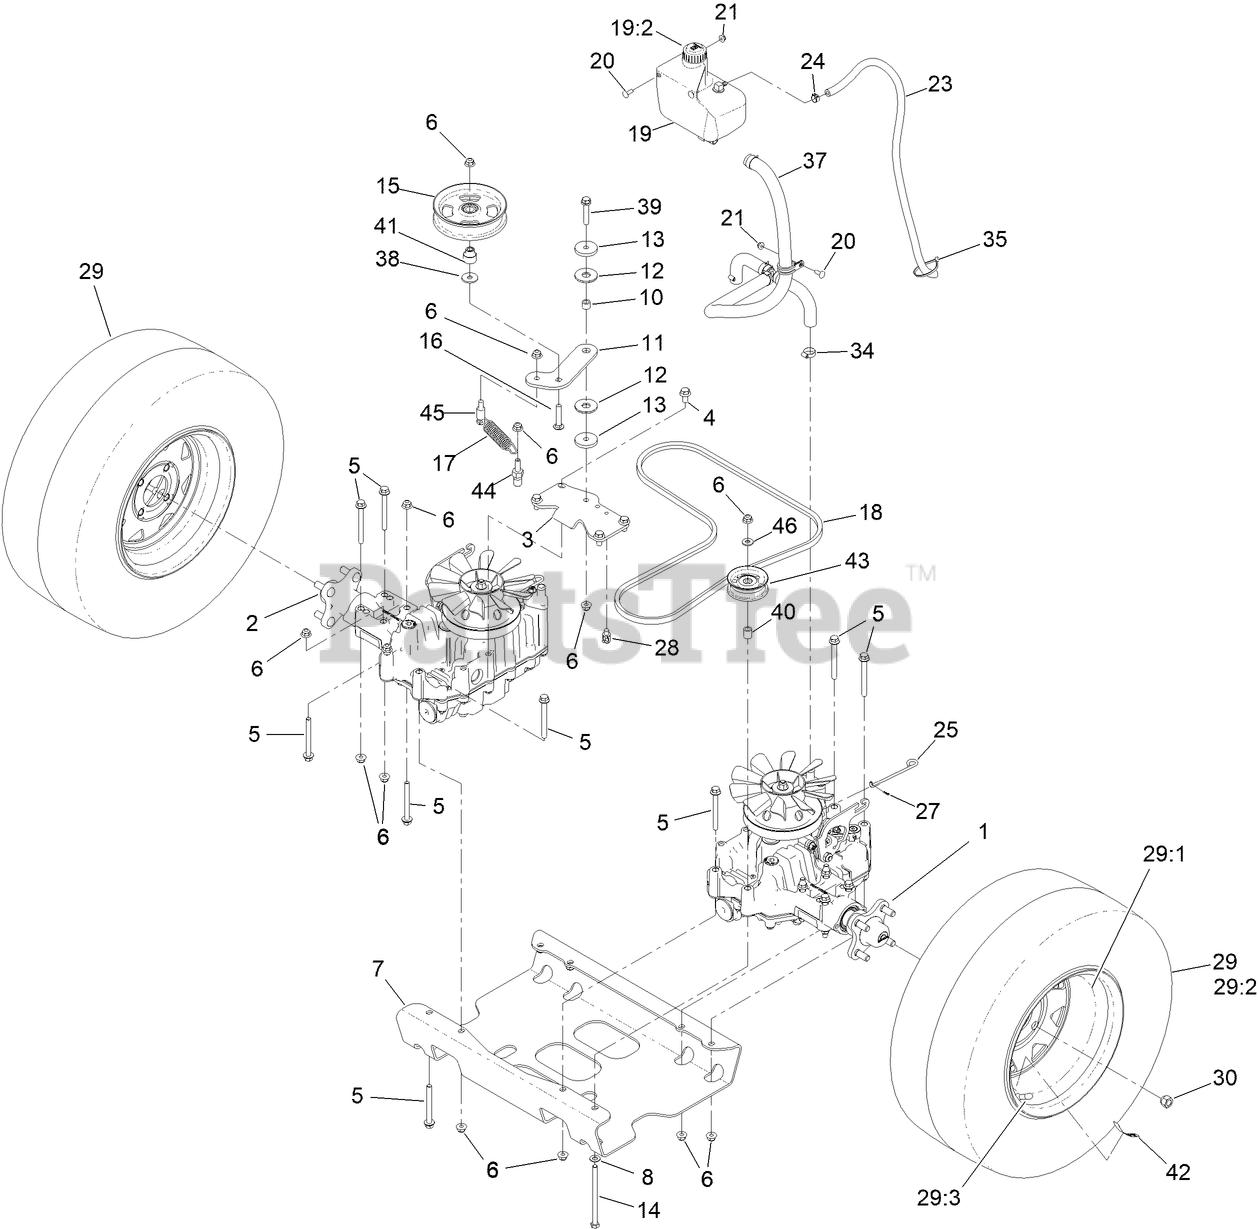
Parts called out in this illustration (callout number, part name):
1	LH TRANSMISSON (TZT13SY)
2	RH TRANSMISSON (TZT13SX)
3	PLATE, SUPPORT, TRANSAXLE
4	SCREW-BSHS
5	SCREW-HHF
6	NUT-HF, NI
7	PLATE-HYDRO
8	WASHER-FLAT
10	BUSHING-LEVER, LIFT
11	PLATE-ARM, IDLER
12	WASHER-FRICTION, COMPOSITE
13	WASHER-PLAIN
14	SCREW-HH
15	PULLEY-IDLER,FLAT
16	SCREW-CARR
17	SPRING-EXTENSION
18	BELT-V
19	TANK-HYD
19:2	CAP-VENTED
21	NUT-HF
23	HOSE-FUEL
24	CLAMP-HOSE
25	ROD-BYPASS
27	PIN-HAIR
28	CLIP-TIE
29	WHEEL AND TIRE ASM
30	NUT-LUG
34	CLAMP-HOSE
35	TIE-CABLE
37	HYD HOSE ASM
38	WASHER-HARDENED
39	SCREW-HHF
40	SPACER-WHEEL
41	BUSHING-IDLER
42	DECAL-TORQUE, WHEEL HUB LUG
43	PULLEY-IDLER, FLAT
44	PIN-ANCHOR, SPRING
45	ANCHOR-SPRING
46	WASHER-FLAT
